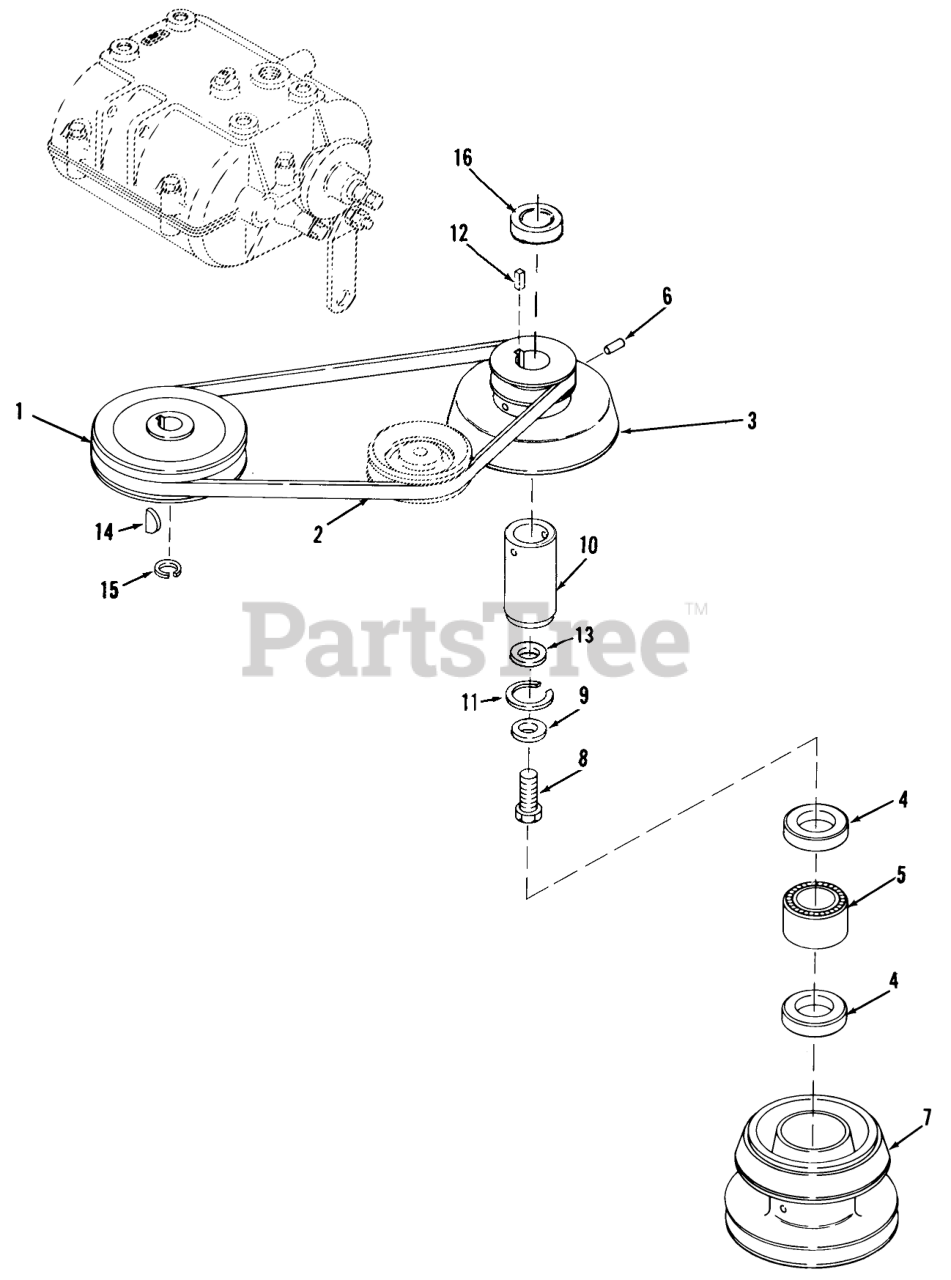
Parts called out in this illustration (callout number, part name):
1	PULLEY
4	SEAL-OIL
5	BRG-NEEDLE OPEN END
6	SPIROL PIN 3/16X9/16
8	HEX HD CAP SCREW
11	RETAIN RING
12	KEY-SQUARE
13	SHIM-WASHER
15	SNAP RING- 5/8 EXT
